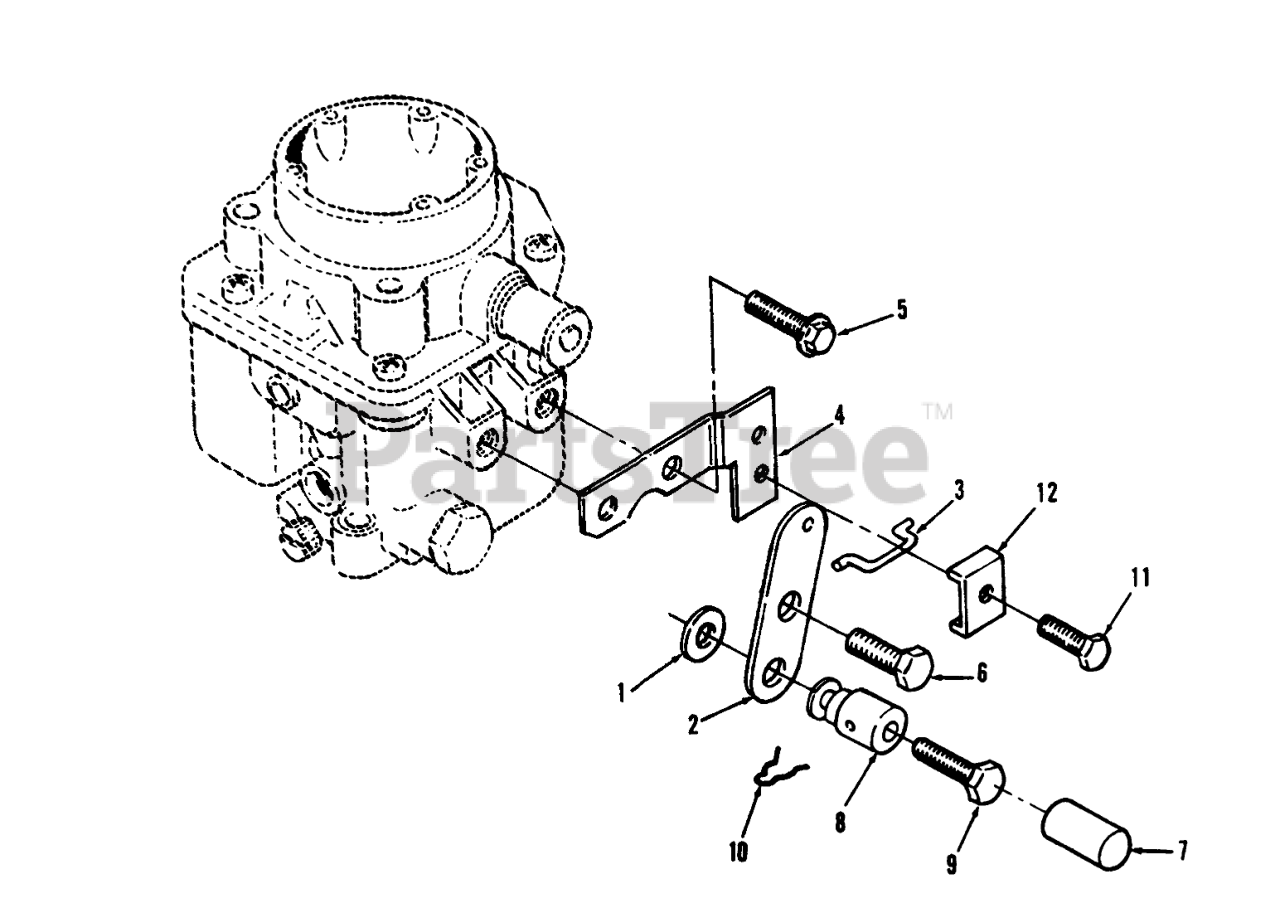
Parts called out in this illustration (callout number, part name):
1	Washer
2	Lever
3	Link
4	Bracket
5	Bolt
6	MACHINE SCREW
8	Swivel
9	Bolt
10	PIN-COTTER
11	SCREW-TAPPING
